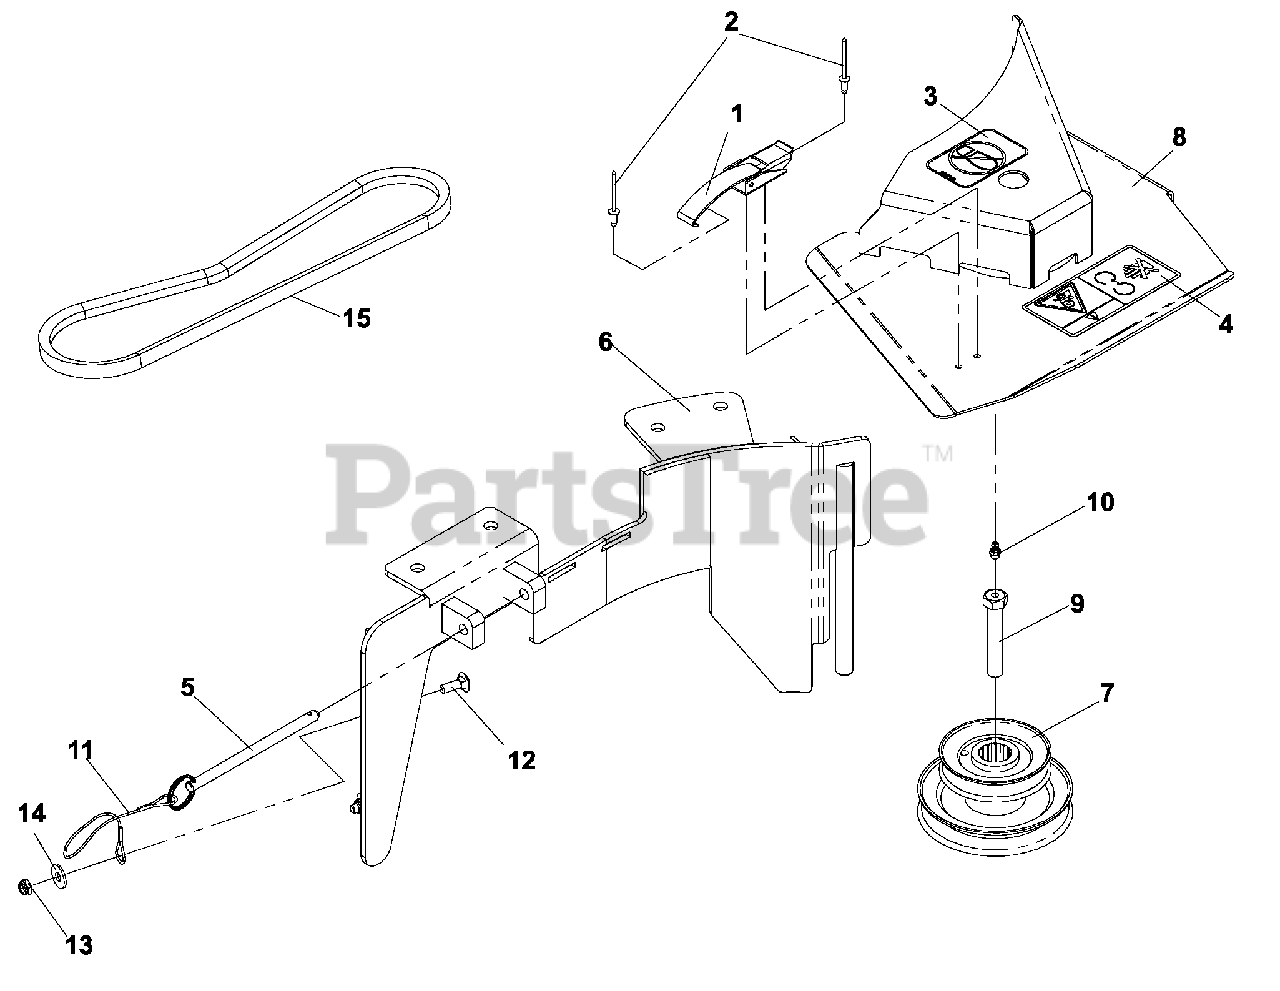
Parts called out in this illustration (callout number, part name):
1	DRAW LATCH
2	RIVET, BLIND, DOME STYLE, 5/32 DIA.
3	DECAL, NO STEP
4	DECAL, DANGER BELT DRIVES
6	BLOWER DECK PLATE, 42/48
7	PULLEY, STACKED DOUBLE, 42/48
8	BELT SHIELD W/DECALS & LATCH, 48"
9	HCS, 7/16-20 X 2 1/2, GR5, SPEC.
10	ZERK
12	RHSNB, 1/4-20 X 3/4, GR2
13	WASHER, 1/4
14	NUT, 1/4C, THIN NYLOC
